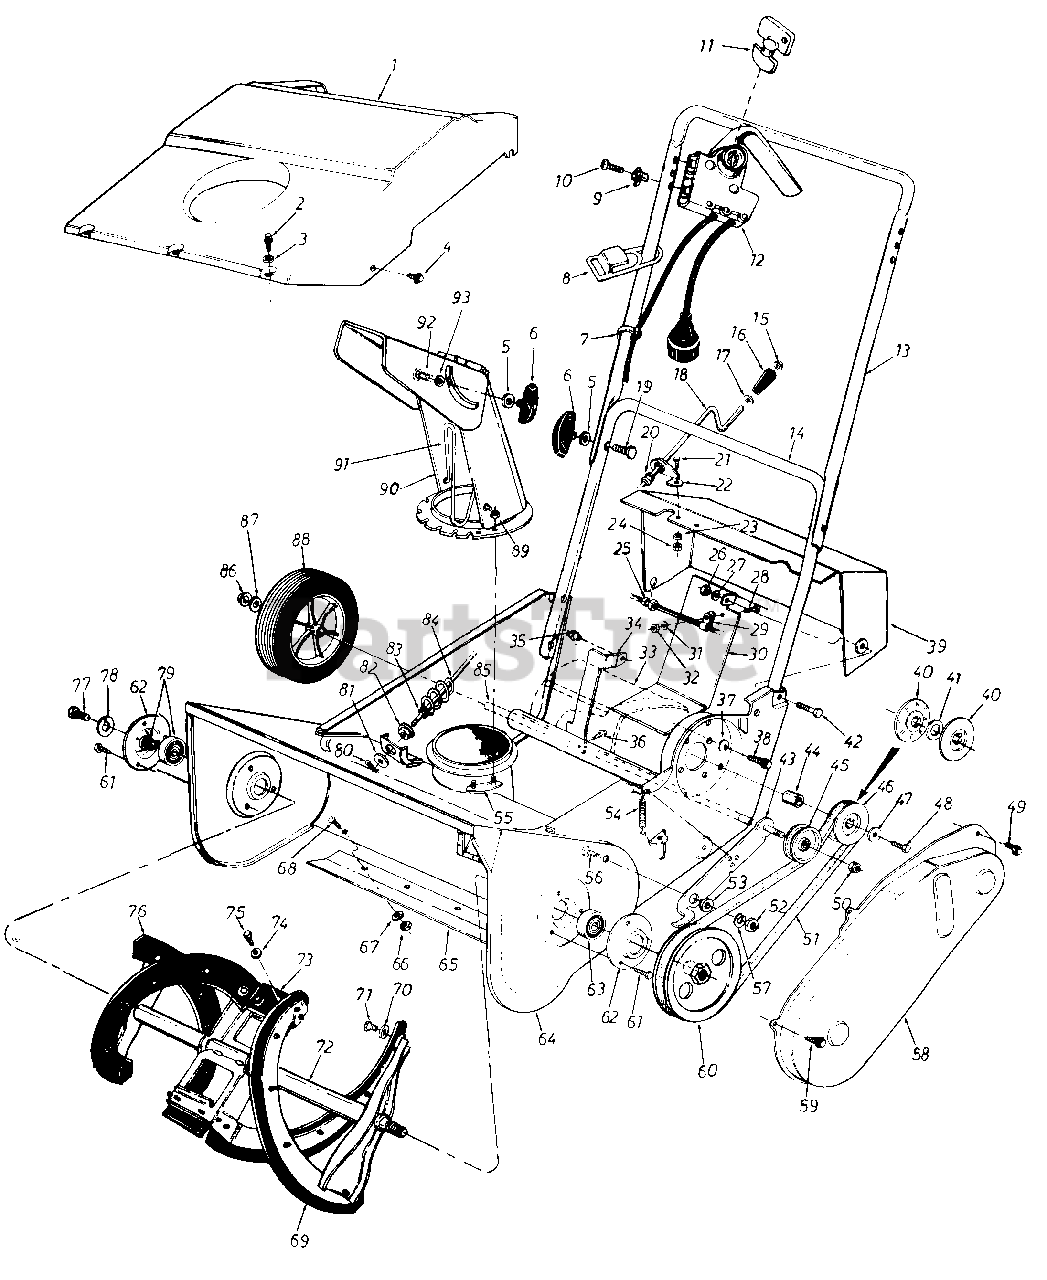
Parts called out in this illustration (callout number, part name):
1	21" Snow Thrower Shroud
2	Hex B-Tap Scr. #10 x .38"
3	Spr.-Wash. .206" I.D. x .448" O.D.
4	Hex L-Wash. Hd. AB-Tap Scr. 1/4 x .62" Lg.
5	Bell-Wash. .345" I.D. x .88" O.D.
6	Hand Knob
7	Cable Tie
8	Cord Restraint
9	Insulating Spacer
10	Fl-Countersunk Scr. #10-24 x 1.5" Lg.
12	Electric Control w/Key
13	Upper Handle
14	Lower Handle
15	Push Nut for 3/8" Rod
16	Knob
17	Fl-Wash. .385 I.D. x .62" O.D.
18	Chute Crank Ass'y. L.H.
19	Curved Hd. Bolt 5/16-18 x 1.75" Lg.
20	Chute Crank Grommet
21	Hex Bolt 1/4-20 x .50" Lg.
22	Upper Chute Crank Brkt.
23	L-Wash. 1/4" I.D.
24	Hex Nut 1/4-20 Thd.
25	Cord Restraint
26	Hex Nut 5/16-18 Thd.
27	L-Wash. 5/16" I.D.
28	Truss Mach. Scr. #10-24 x .50" Lg.
29	Cord Restraint
30	21" Blower Housing Ass'y.
31	Ext. L-Wash. #10
32	Hex Nut #10-24 Thd.
33	Electric Motor 120V
34	Motor Support Brkt.
35	Motor Shroud w/Hdwe.
36	Hex L-Wash. Hd. AB-Tap 1/4 " x .62" Lg.
37	L-Wash. 5/16" I.D.
38	Hex Bolt 5/16-18 x .50" Lg.
39	Dash Panel
40	3/8-V-Pulley Half .625" I.D. x 2.25
41	Bell-Wash. .345" I.D. x .88" O.D.
42	Hex Bolt 5/16-18 x 1.50" Lg.
43	Idler Brake Brkt. Ass'y.
44	Spacer .635" I.D. x .890" O.D. x .80" Lg.
45	Fl-Idler w/Flanges 2.12" O.D.
46	3/8-V-Pulley Half .625" I.D. x 2.25
47	Bell-Wash. .345" I.D. x .88" 0. D.
48	Hex Bolt 5/16-24 x .75" Lg.
49	Hex L-Wash. Hd. AB-Tap 1/4 " x .62" Lg .
50	Hex Patch L-Nut 3/8-24 Thd.
51	V-Belt 1/2" X 34.0" Lg.
52	Hex Nut 5/16-18 Thd.
53	Shld. Spacer .500" Dia. x .27" Lg.
54	Extension Spring
55	Chute Flange Keeper Ass'y.
56	Truss Mach. Scr. 5/16-18 x .75" Lg.
57	L-Wash. 5/16" I.D.
59	Hex B-Tap Scr. 1/4 X .38" Lg.
60	Flat Pulley 5.06" O.D. 1/2-20 L.H.
61	Hex B-Tap Scr. 1/4 X .38" Lg.
64	21" Blower Housing Ass'y.
65	Shave Plate
66	Hex Nut 1/4-20 Thd.
67	Bell-Wash. .265" I.D. x .75" O.D.
68	Carriage Bolt 1/4-20 x .62"
69	Rubber Spiral 8.62" Dia. L.H.
70	Fl-Wash. .281" I.D. x .50" 0. D.
71	Hex Wash. B-Tap Scr. 1/4 x .62" Lg. Spec.
72	Auger Ass'y. 21 " 8.62" Dia.
73	Rubber Paddle
74	Fl-Wash. .218" I.D. x .62" O.D.
75	Hex Wash. B-Tap Scr. #10 x .62" Lg.
76	Rubber Spiral 8.62" Dia. R.H.
77	Hex Wash. TT-Tap Cl-Scr. 1/4-20 x .75" Lg.
78	L-Wash. 1/4" I.D.
79	Kit Bearing and Collar
80	Cot-Pin 3/32 Dia. x .75" Lg.
81	Fl-Wash. .385" I.D. x 1.50" O.D.
82	Hex Bushing .385" I.D.
83	Fl-Wash. .385" I.D. x .62" O.D.
84	Chute Crank Ass'y. L.H.
85	Wheel Axle Tubing
86	Push Cap 1/2" Dia.
87	Fl-Wash. .510" I.D. x .75" O.D.
88	Plastic Wheel Ass'y. 6 x 1.50"
89	Hex L-Nut 1/4-20 Thd.
90	5.0" Dia. Chute Ass'y.
91	Chute Ass'y. Guard
92	Carriage Bolt 5/16-18 x .62" Lg.
93	Fl-Wash. .328 I.D. x .68" O D
